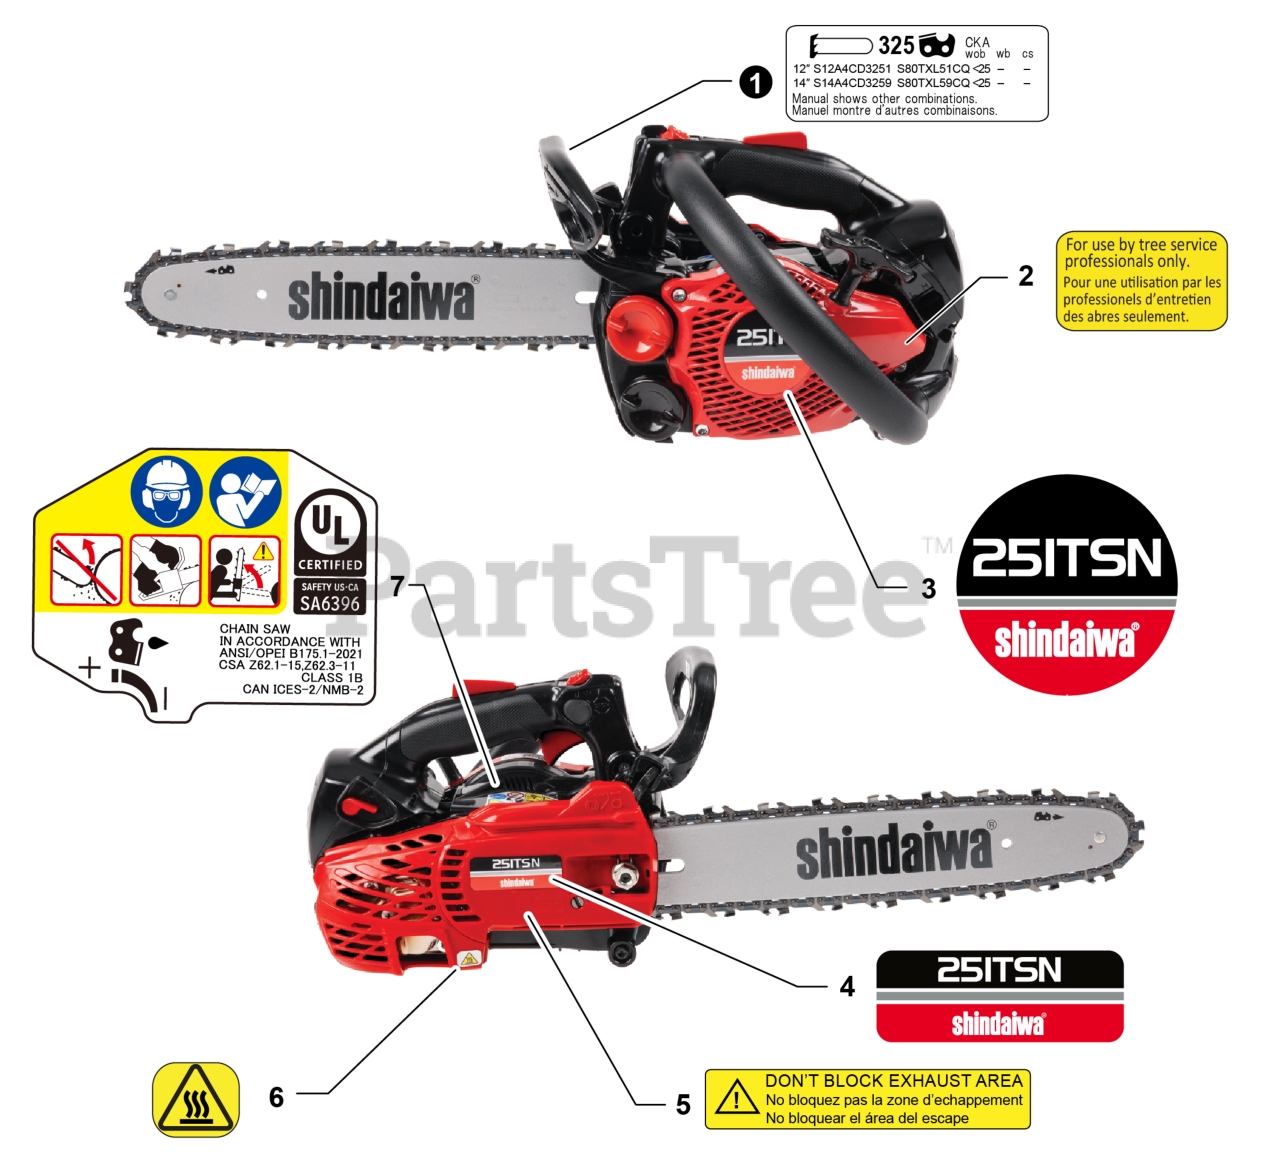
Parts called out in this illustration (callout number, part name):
1	LABEL - BAR & CHAIN
2	LABEL - CAUTION - PROFESSIONALS ONLY
3	LABEL - RECOIL STARTER 251TSN
4	LABEL - MODEL 251TSN
5	LABEL - CAUTION - DON'T BLOCK EXHAUST AREA
6	LABEL - CAUTION - HOT
7	LABEL - CAUTION - UL
